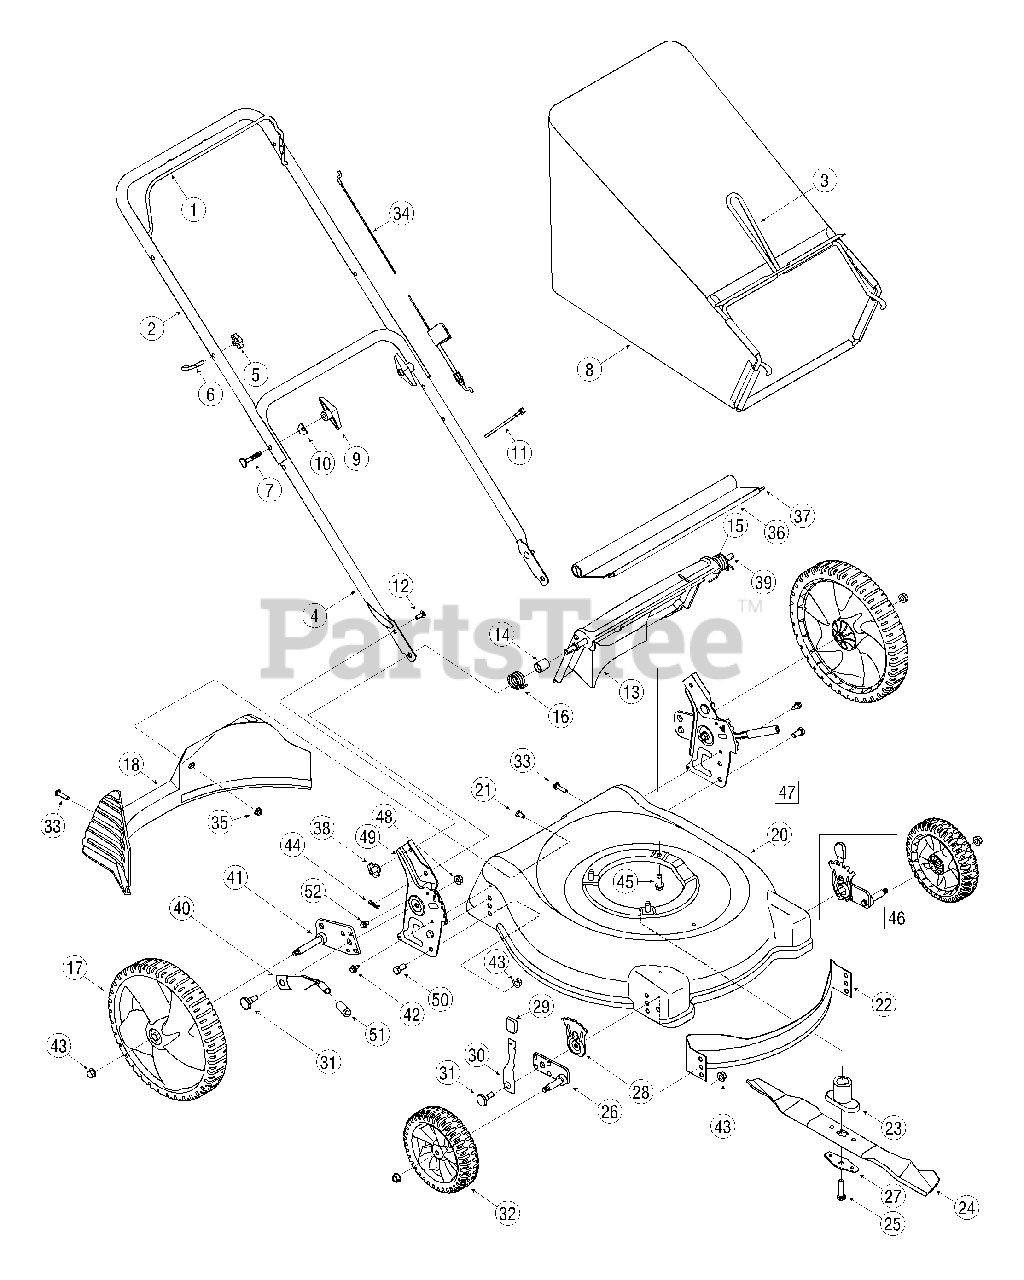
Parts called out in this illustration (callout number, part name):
5	Wing Nut
6	Rope Guide
7	Carriage Bolt ,5/16-18
8	Grass Bag Assembly
9	Hand Knob
10	Saddle Washer
11	Cable Tie
12	Carriage Bolt ,1/4-20
13	Rear Discharge Door
14	Spacer
15	Torsion Spring - LH
16	Torsion Spring - RH
17	Rear Wheel, 12 x 1.8
18	Rear Baffle
22	Front Baffle
23	Blade Adapter
24	Mulching Blade
25	Hex Screw, 3/8-24 x 2.5
26	Pivot Arm Assembly - RH
27	Blade Bell Support
28	Front Adjustment Plate
29	Adjustment Lever Knob
30	Spring Lever Assembly
31	Shoulder Screw
32	Front Wheel, 7 x 1.8
33	Screw, 1/4-15 x 1.250
34	Control Cable - 40"
35	Flange Lock Nut, 1/4-20
36	Trailshield
37	Trailshield Wire
38	Wing Nut, 1/4-20
39	Rear Door Pivot Rod
40	Spring Lever
41	Pivot Arm Assembly - RH
42	AB Screw
43	Flange Lock Nut, 3/8-16
44	Hairpin Clip
45	TT Sems Screw, 3/8-16 x 1.0
46	Ht. Adj. Assy. Front - LH
47	Rear Handle Bracket Assy. - LH
48	Flange Lock Nut, 3/8-16
49	Handle Bracket Assembly - RH
50	Hex Screw, 3/8-16 x 0.75
51	Spring Lever Grip
52	Screw, 1/4-20 x .500
